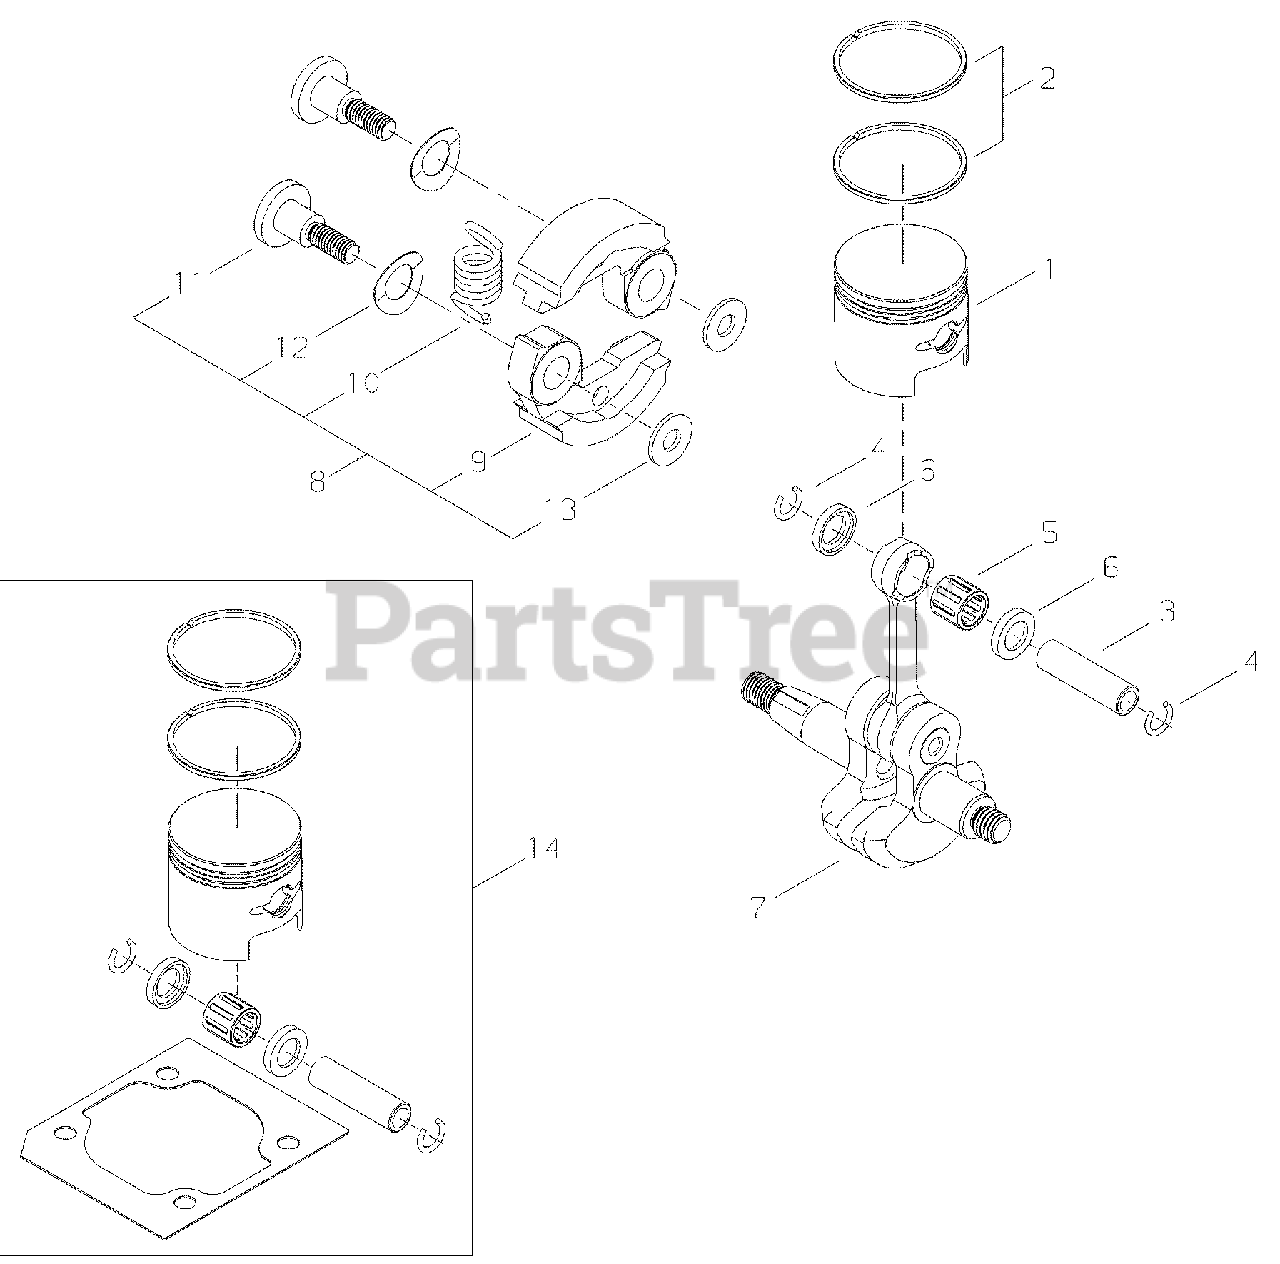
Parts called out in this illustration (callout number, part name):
1	PISTON
2	RING, PISTON
3	PIN, PISTON 8
4	RING, SNAP
5	BEARING, NEEDLE 8
6	WASHER, THRUST 8
7	CRANKSHAFT ASSY
8	SHOE ASSY, CLUTCH
9	SHOE, CLUTCH
10	SPRING, CLUTCH
11	BOLT, CLUTCH
12	WASHER, SPRING
13	WASHER 6 MM
14	PISTON KIT
